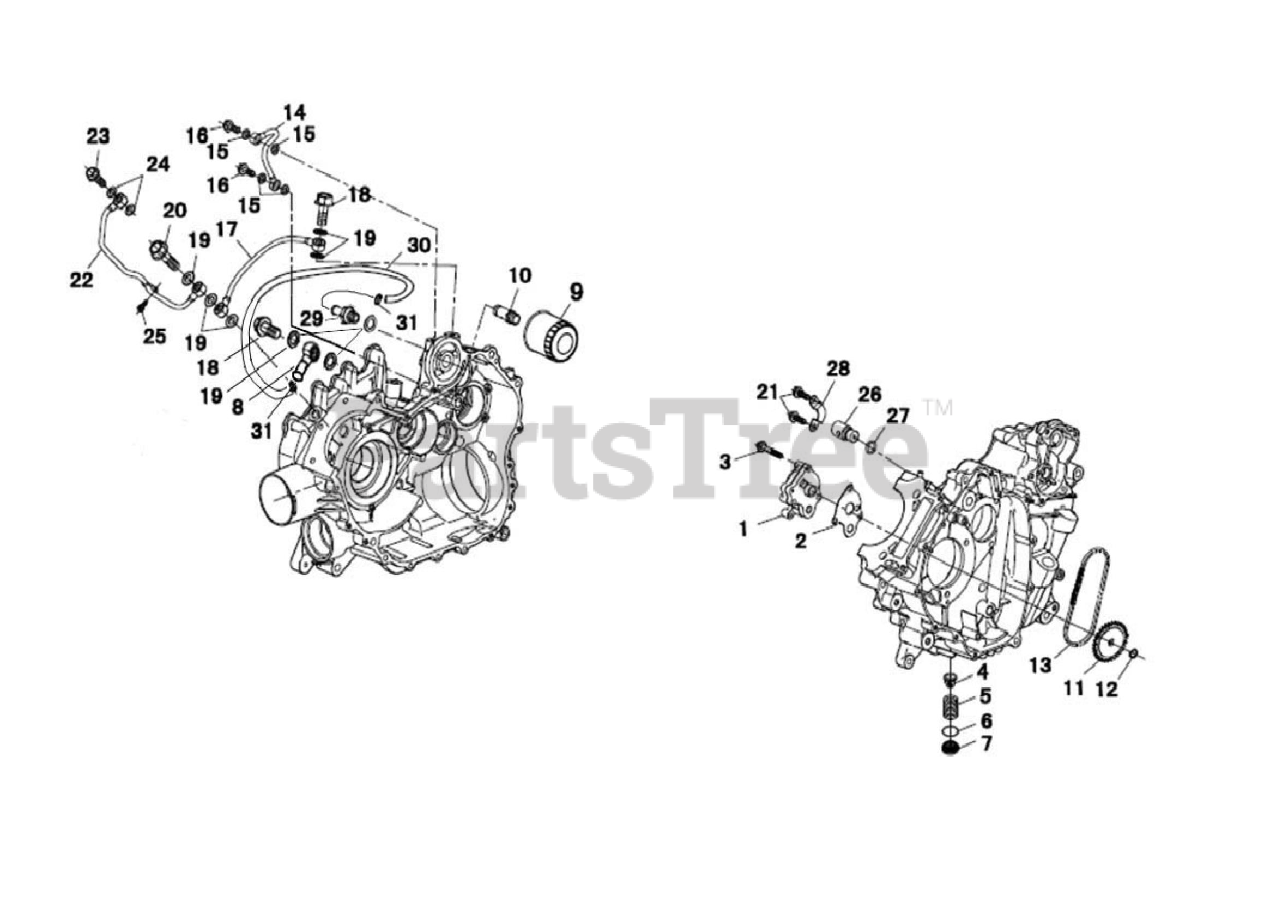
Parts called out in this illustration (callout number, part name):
1	Oil Pump Assy
2	Gasket,Oil Pump
3	Hex flange bolts M6X40
4	Oil Filter Strainer
5	Filter Spring
6	O-Ring 36X3.5
7	Blind Nut,Oil Drainage
8	BANJO BOLT
9	Oil Filter
10	Filter joint
11	Oil Pump Driven Sprocket
12	Circlip for shaft ?11
13	Chain,Oil Pump
14	Oil Tube Welding Assy A
15	Aluminum Washer 8X15X2
16	Bolts for oil tube M8X25
17	Oil Tube Welding Assy B
18	Bolts for oil tube M14X1.5X28
19	Aluminum Washer 14X20X1.5
20	Bolts for oil tube M14X1.5X50
21	Hex flange bolts M6X14
22	OIL TUBE WELDING ASSEMBLY
23	Bolts for oil tube M10X1.25X30
24	Aluminum Washer 10X16X1.2
25	Hex flange bolts M6X12
26	Pressure Regulating Valve Assy,Engine Oil
27	O-Ring 10X2.45
28	Press Plate,Pressure Regulating Valve
29	Oil Pipe Joint
30	RUBBER PIPE
31	Lock Clamp A
